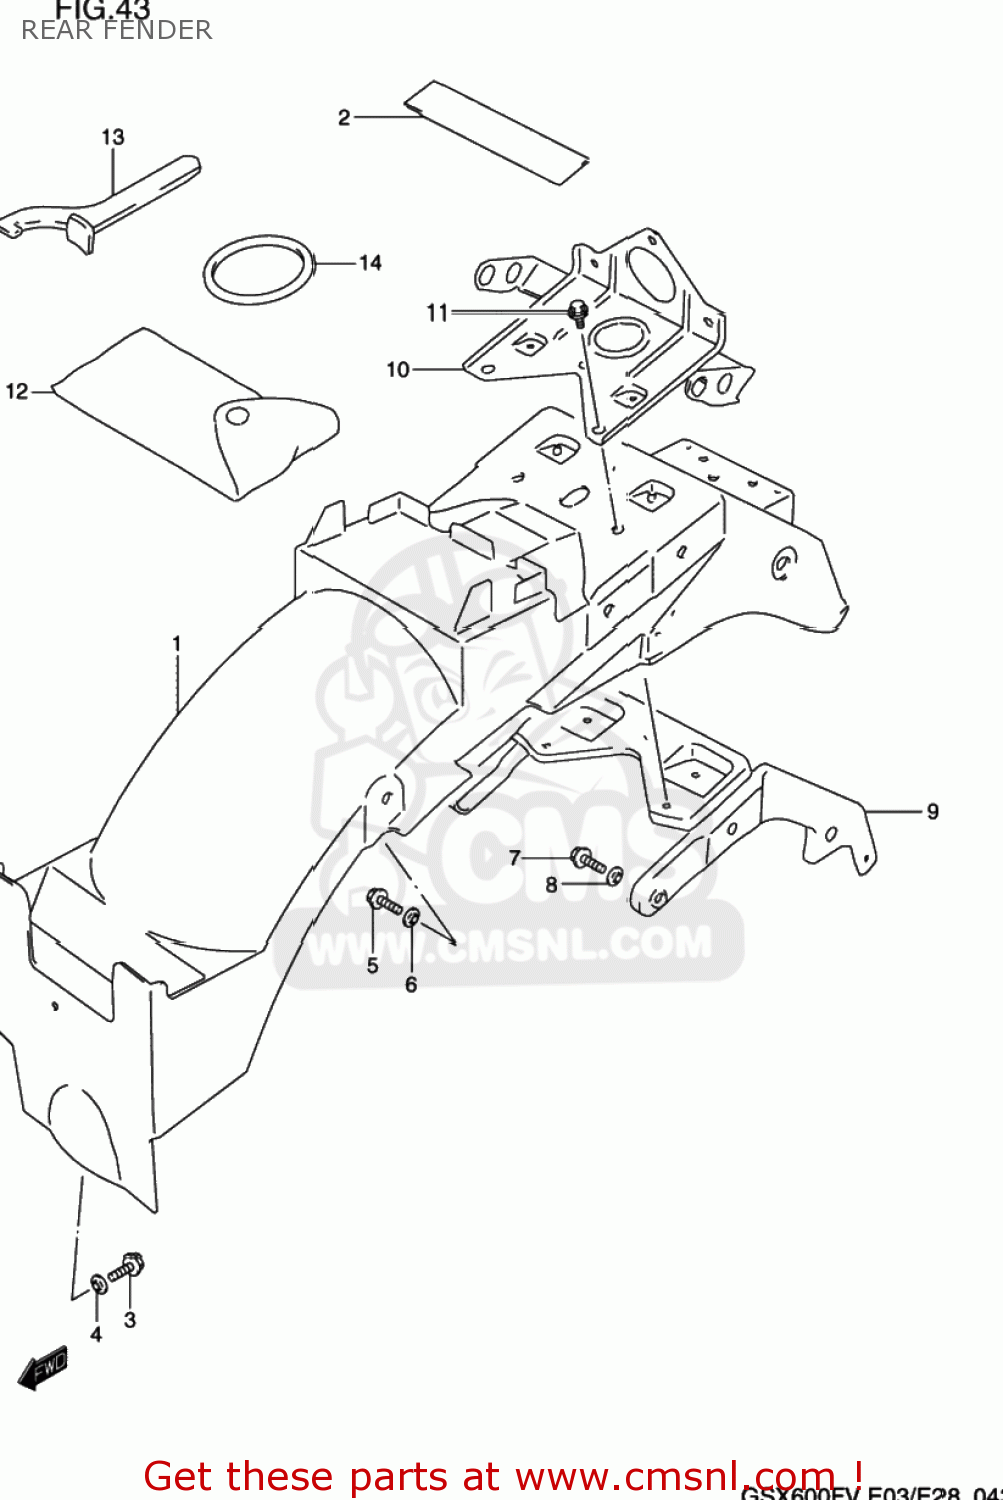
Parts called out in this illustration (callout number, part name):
1	BODY,REAR FENDER
2	CUSHION,RR FENDER
3	BOLT
4	WASHER
5	BOLT
6	WASHER
7	BOLT
8	WASHER
9	REINF,RR FENDER
10	BRACKET,RR LAMP
11	BOLT
12	TOOL ASSY
13	CLAMP
14	O RING(D:3.5,ID:61)
